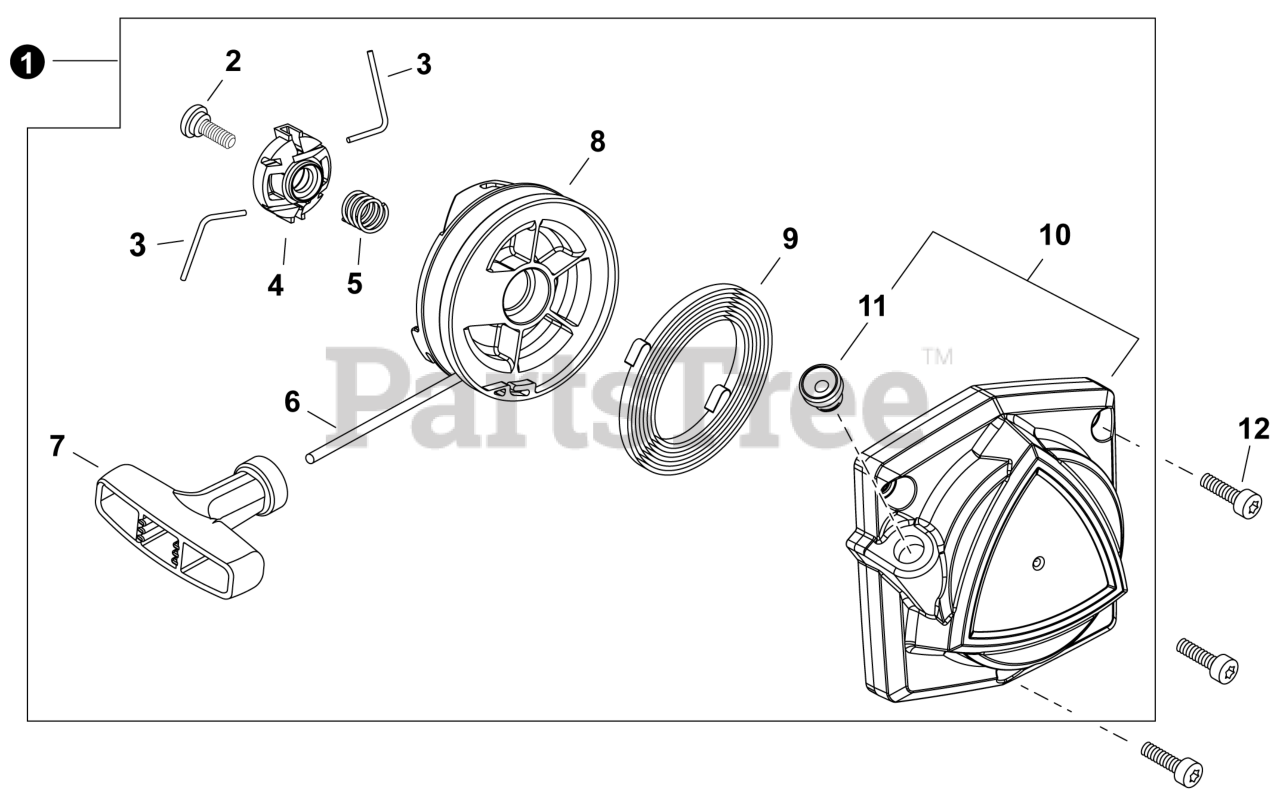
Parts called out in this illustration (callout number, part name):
1	STARTER ASSY, RECOIL
2	SCREW 5
3	RATCHET, STARTER
4	COLLAR, RATCHET
5	SPRING, SPIRAL
6	ROPE, STARTER
7	GRIP, STARTER
8	REEL, ROPE
9	SPRING, SPIRAL
10	STARTER CASE ASSY
11	GUIDE, ROPE
12	BOLT, TORX 5x20
